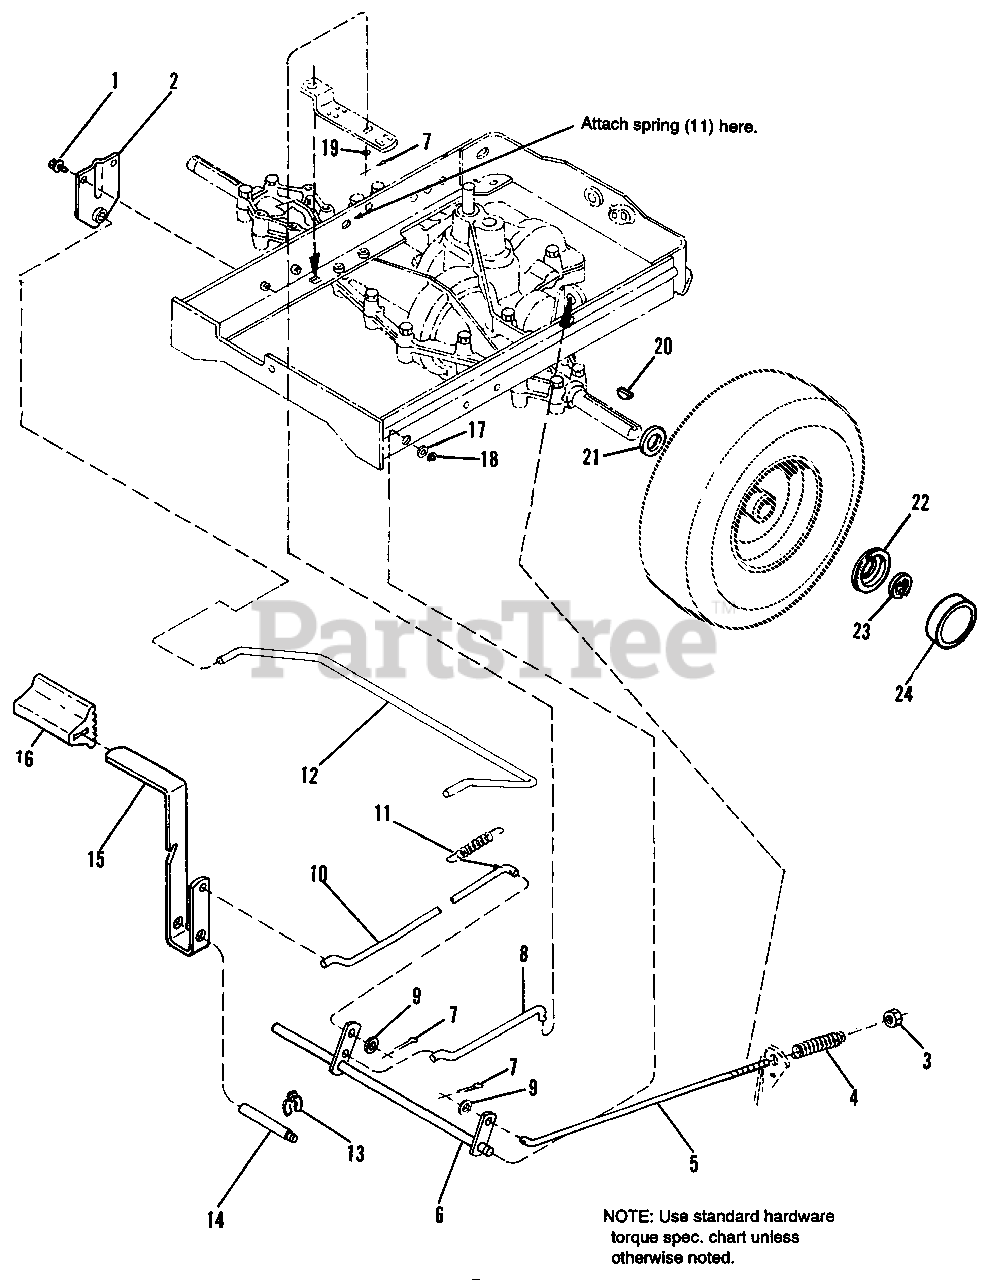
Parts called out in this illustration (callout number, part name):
1	SCREW, Hex Hd., Flange Taptite, 5/16-18 x 1/2
2	BRACKET, Torsion Bar
3	NUT, Hex, Lock, Esna, 5/16 x 18
4	SPRING, Compression
6	PIVOT SHAFT ASSY.
7	PIN, Cotter, 3/32 x 3/4
8	ROD, Clutch, Rear
9	WASHER, Plain, 5/16
10	ROD, Clutch, Front
11	SPRING, Clutch Lever
12	TORSION BAR
13	KLIPRING, 3/8
14	PIVOT, Brake
15	LEVER, Clutch
16	PAD, Pedal
17	WASHER, Plain, 1/2
18	KLIPRING, 1/2
19	WASHER, Plain, 5/16
20	KEY
21	WASHER, 3/4
22	RETAINER, Hubcap
